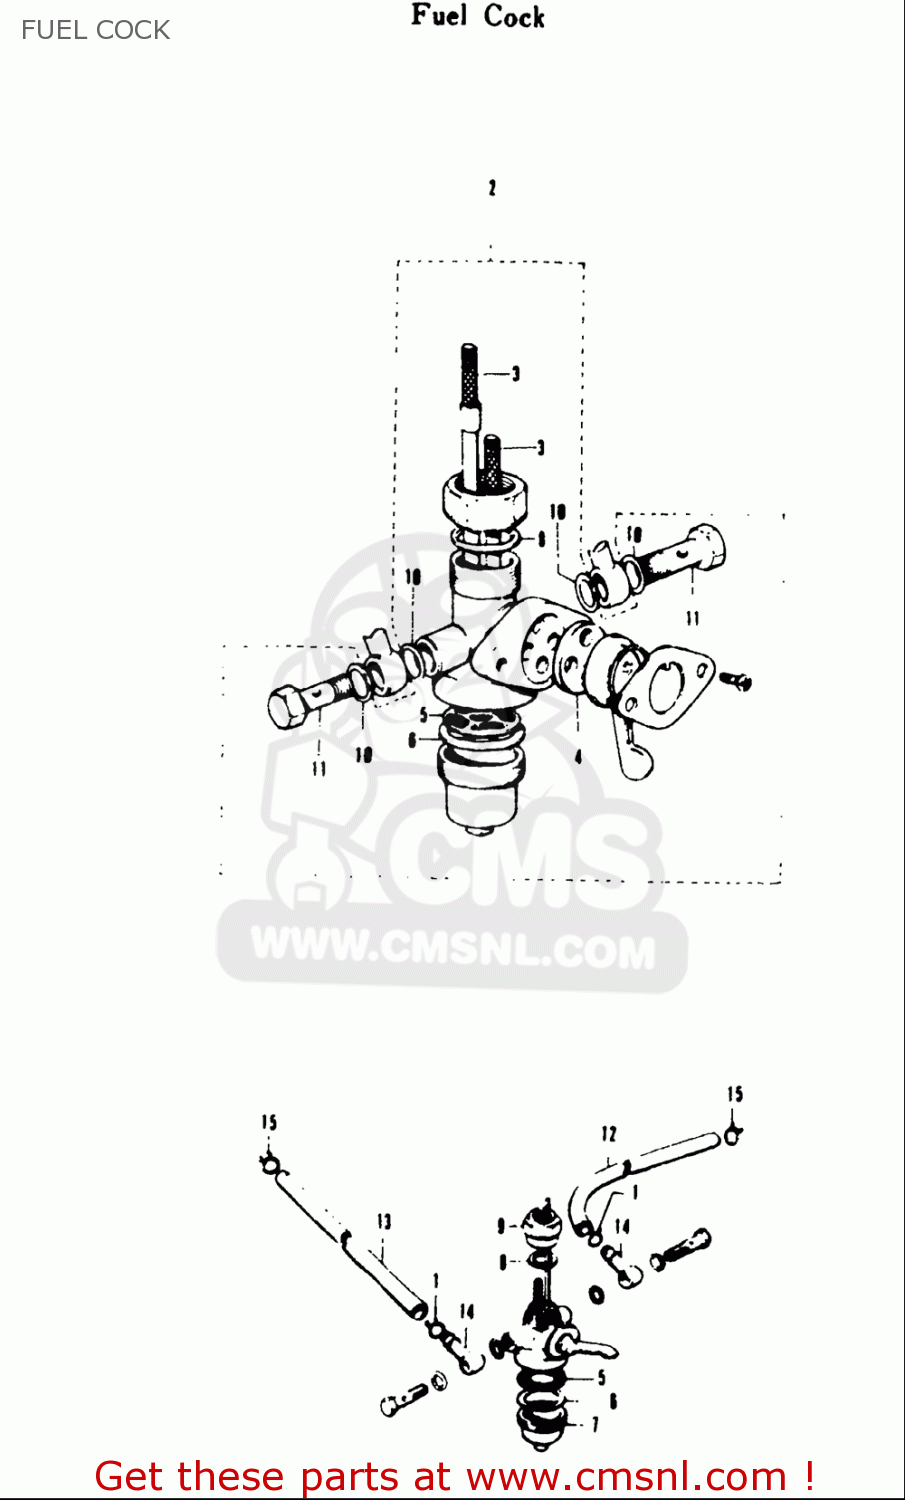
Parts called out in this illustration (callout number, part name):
3	FILTER SET,FUEL COCK
4	GASKET,LEVER (NAS)
8	GASKET,FUEL COCK (NAS)
